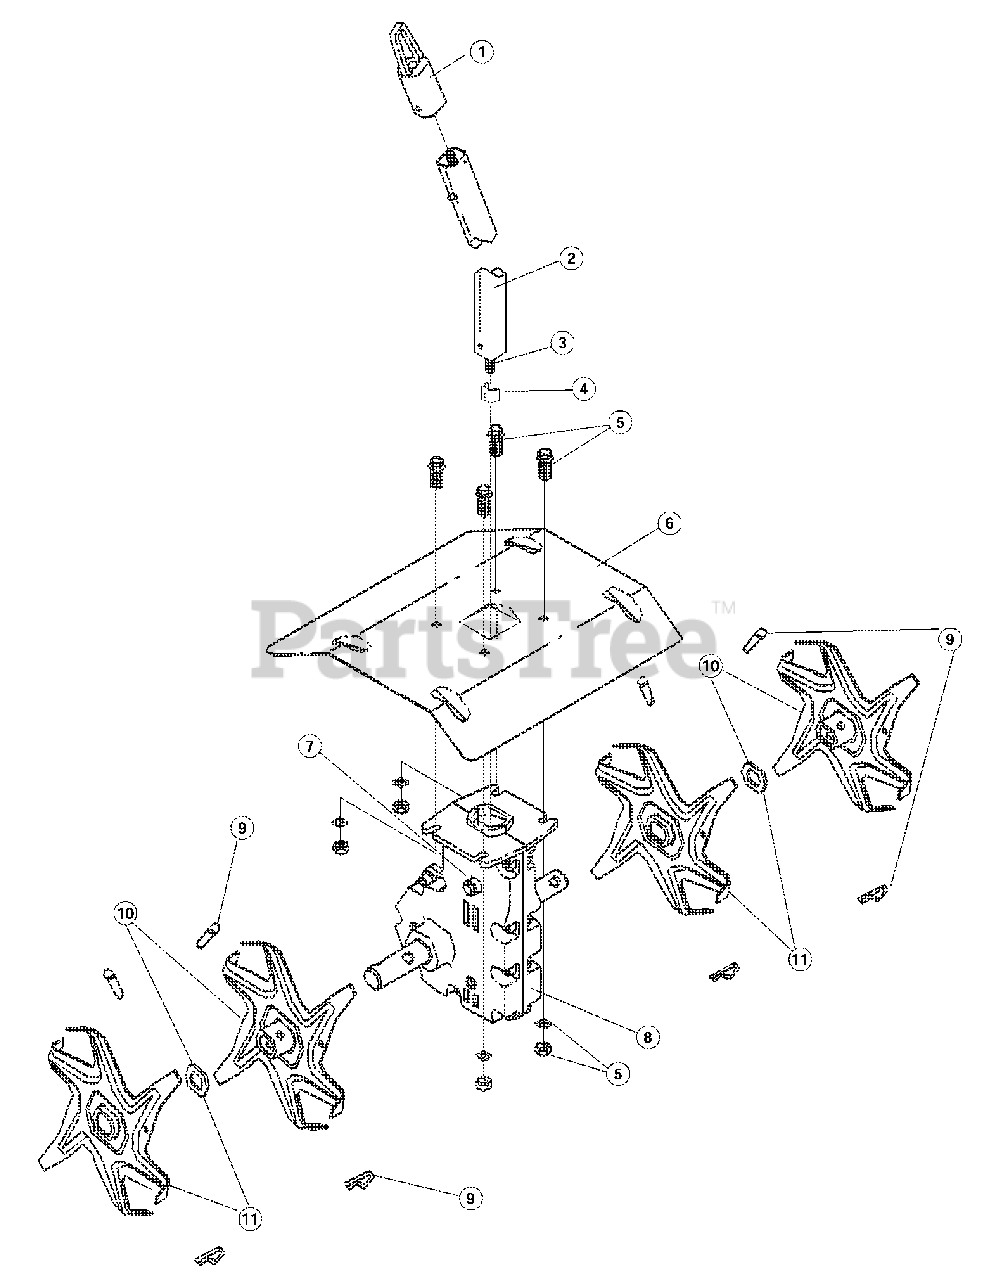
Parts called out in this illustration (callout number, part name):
1	Accessory Hanger
2	Drive Shaft Housing Assembly
3	Flexible Drive Shaft
4	Retainer Sleeve
5	Guard Mounting Hardware Set
7	Bolt
8	Gear Box Assembly
9	Tine Fastener Assembly
10	Tine Assembly
11	Tine Assembly
